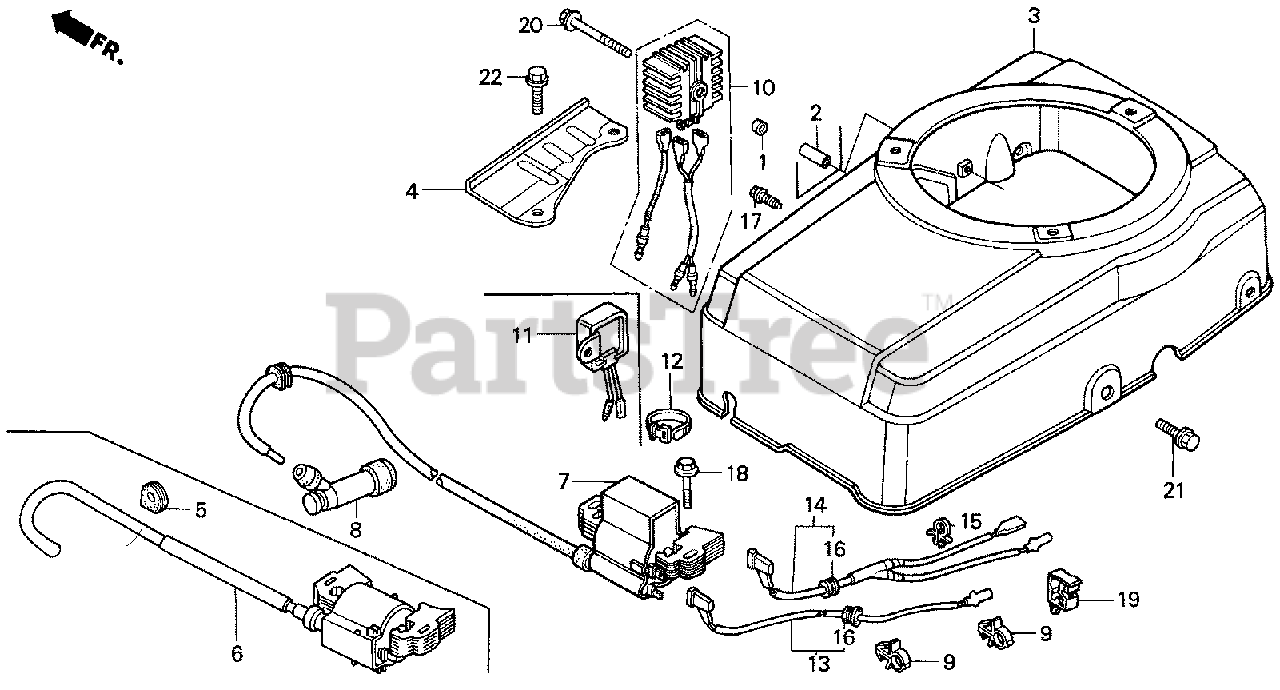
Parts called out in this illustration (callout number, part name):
3	COVER, FAN *R8* (Honda Code 4542494). (BRIGHT RED)
4	PLATE, SIDE
5	GROMMET, WIRE
6	COIL ASSY., IGNITION
7	COIL ASSY., IGNITION
8	CAP ASSY., NOISE SUPPRESSOR
9	CLIP, IGNITION WIRE (8MM)
14	WIRE, STOP SWITCH
16	GROMMET, WIRE
17	BOLT, FLANGE (6X12) (CT200)
18	BOLT, FLANGE (6X28)
21	BOLT, FLANGE (8X16)
22	BOLT, FLANGE (8X20)
23	CLIP A, BRAKE PIPE
